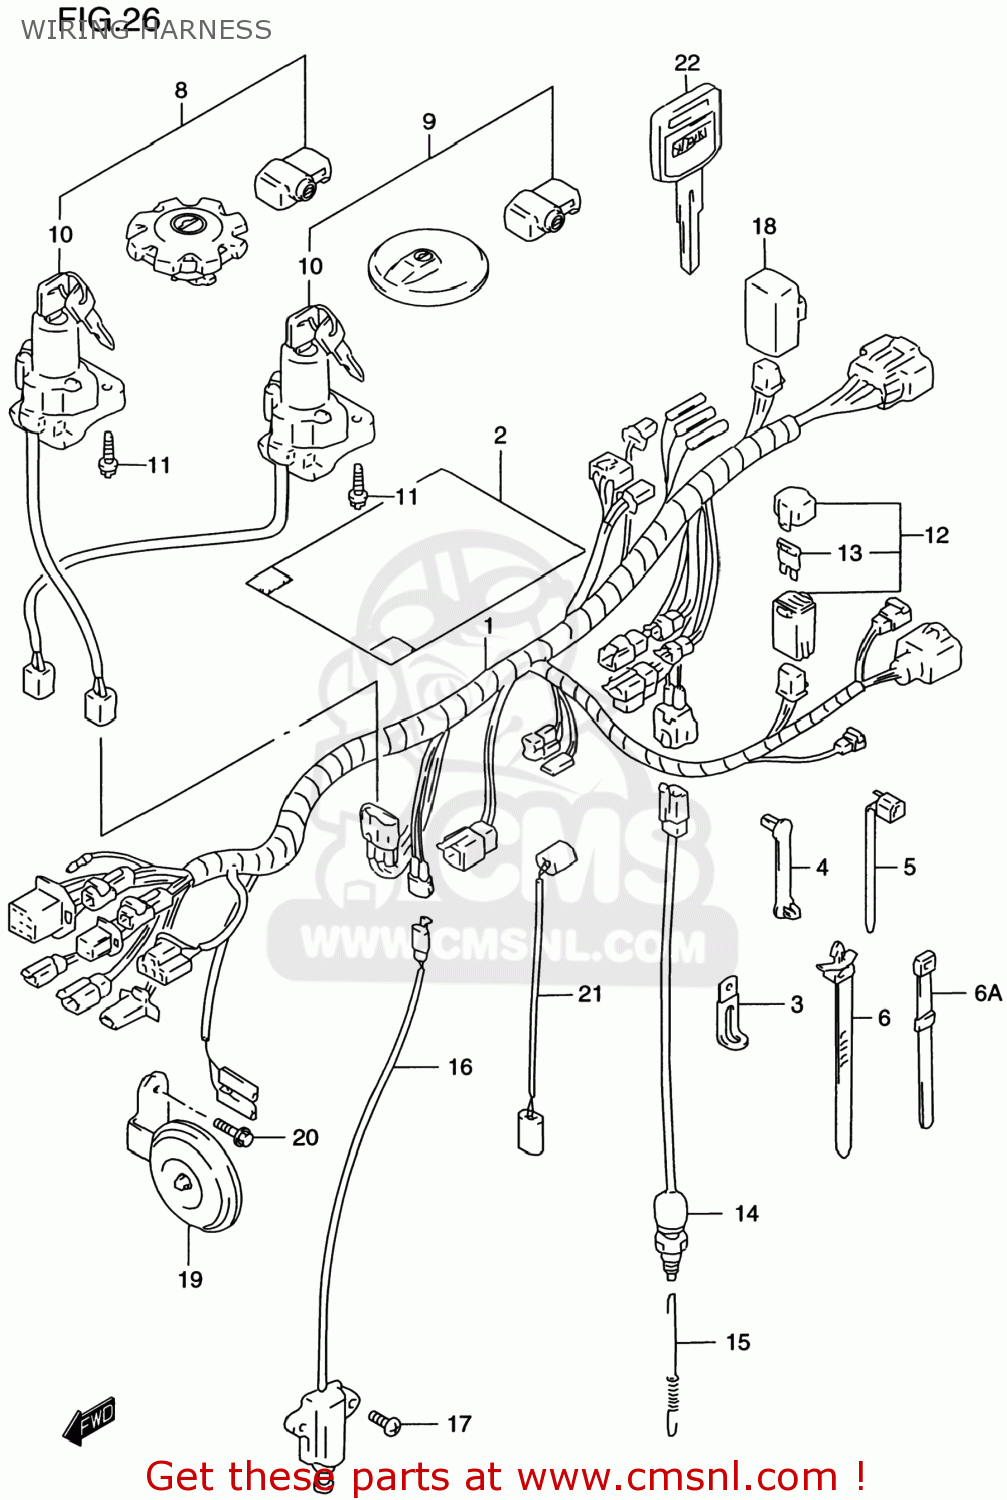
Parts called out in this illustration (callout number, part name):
1	HARNESS,WIRING
2	COVER,WIRING HARNESS
3	CLAMP(L:45)
4	CLAMP(L:33)
5	CLAMP(L:95)
6	CLAMP(L:90)
6A	CLAMP(L:120)
7	LOCK ASSY,STEERING
8	LOCK SET
9	LOCK SET
10	LOCK ASSY,STEERING
11	BOLT(8X20)
12	BOX ASSY,FUSE
13	FUSE(10A)
14	SWITCH ASSY,STOP LAMP
15	SPRING
16	SWITCH ASSY,SIDE STAND
17	SCREW 6X16
18	RELAY ASSY
19	HORN ASSY
20	BOLT
21	WIRE,THROTTLE SENSOR
22	KEY,BLANK
